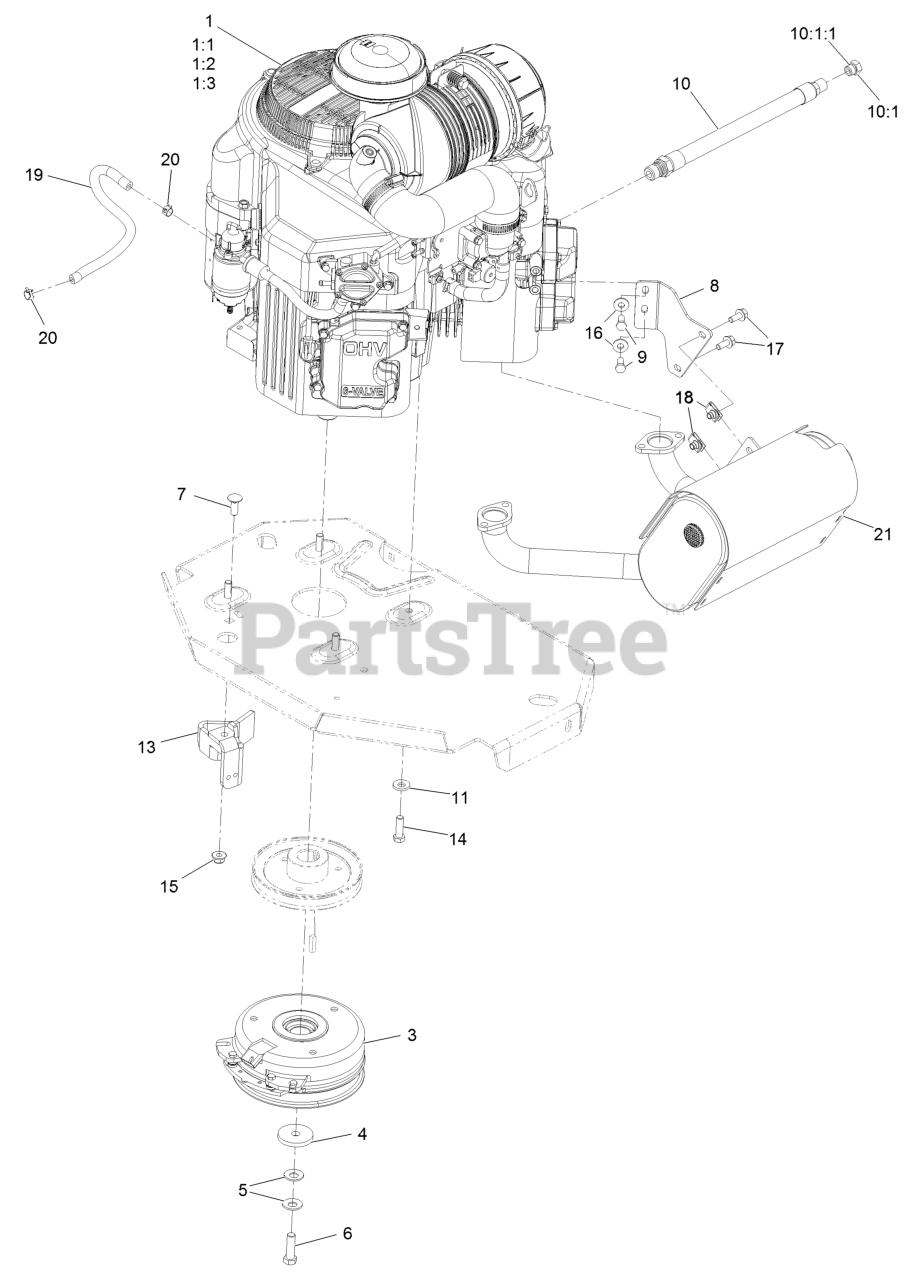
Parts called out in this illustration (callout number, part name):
1:1	Kawasaki 49065-7007 Engine Oil Filter
1:2	Kawasaki 11013-7044 Engine Air Filter
1:3	Kawasaki 11013-7045 Safety Filter
4	WASHER-CLUTCH
5	WASHER-SPRING
6	SCREW-HH 7/16-20 X 1 1/2 W/LOCTITE
7	SCREW-CARR
8	BRACKET-MUFFLER
9	SCREW-HH
10	ENGINE OIL DRAIN HOSE ASM
10:1	PLUG-HH
10:1:1	O-RING
11	WASHER-BELLEVILLE
13	CLUTCH-ANCHOR
14	SCREW-HH
15	NUT-HF, NI
16	WASHER-SPRING
17	SCREW-HHF
19	HOSE-FUEL
20	CLAMP-HOSE
21	MUFFLER
